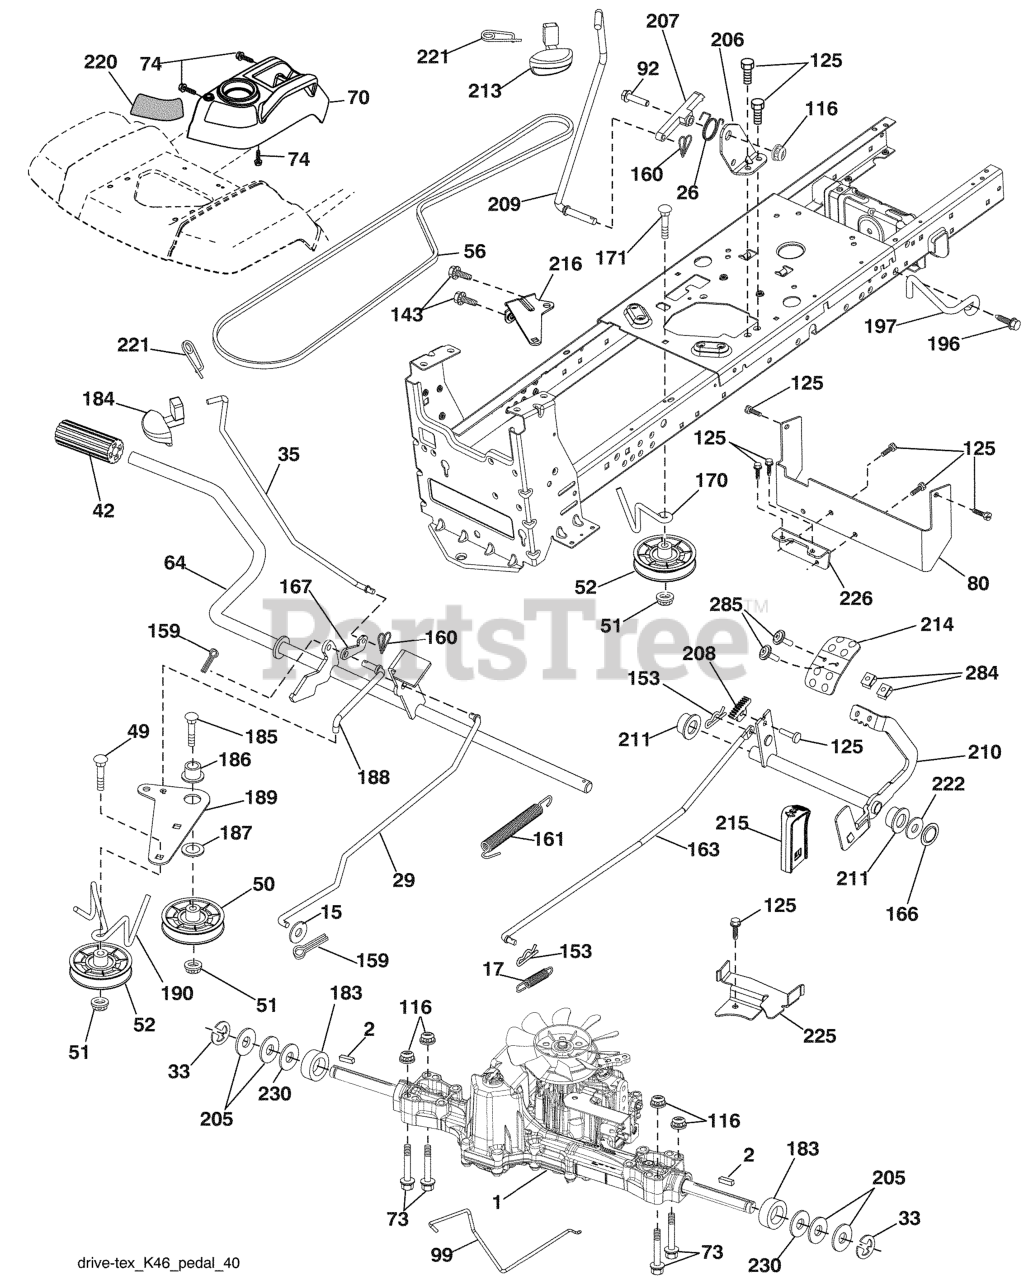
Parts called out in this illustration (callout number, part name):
1	RP TRANSAXLE (K46CR) ETC.PDL
2	SQUARE KEY
15	WASHER
17	SPRING.BRAKE.K46.GREEN
26	SPRING.RETURN.CRUISE
29	ROD.BRAKE.K46
35	ROD.BRAKE.PARKING.GT.H
42	PEDAL COVER T
50	IDLER.FLAT.910.OFFSET
51	NUT LOCK FLG 3/8-16 UNC
52	IDLER.V-GROOVE.910.OFFSET
56	V-BELT.MOWER.92.40.42/K46
64	SHAFT.ASM.PEDAL.BRK.CNTR
70	RP CONSOLE.ASM.PCH.W/TB
73	BOLT HEX 5/16-18 GR 5
74	SCREW.HI-LO.CONSOLE
80	STRAP TORQUE.ASM.K46/18"TEX
92	BOLT
99	ROD.SPRING.BYPASS.K46.LT.Z
116	NUT LOCK HEX FLANGE 5/16-18
125	SCREW
143	Screw 5/16-18 x 1/2
153	RETAINER M
159	COTTER PIN
160	RETAINER CLIP
161	SPRING, RETURN LT
163	ROD.CONTROL.PEDAL.K46
166	NUT.PUSH.625.2006
167	LATCH.BRAKE.SPRING
170	KEEPER.V-IDLER.CENTER.
171	BOLT
183	SPACER AXLE
184	HANDLE.PARKG.BRK.HUSQ X667
186	SPACER.RETAINER
187	WASHER 12/32X2X10GA
188	RP.LINK.CLUTCH.GROUND.DRIVE
189	BELLCRANK.GROUND.DRIVE.TEX.
190	KEEPER.BELLCRANK.DRIVE
196	SCREW 3/8-16X1
197	LINK.CLUTCH.ANIT-ROTAT
206	BRKT.MOUNT.LATCH.CRUIS
207	LATCH.CONTROL.CRUISE
208	GEAR.SECTOR.CONTROL.CR
209	ROD.CONTROL.CRUISE.GT.
210	ROCKER.ASM.PEDAL.CONTR
211	BEARING.NYLON
213	KNOB.CONTROL.CRUSIE.HU
214	PEDAL.FORWARD.HUSQVARNA.DEALER
215	PEDAL.REVERSE.TEX.GT.4
216	BRACKET.PULLEY.IDLER.W/TEX
220	REFLECTOR.RH.TEX GT
221	RETAINER.SPRING.CLIP.H
222	WASHER 21/32 X 1-1/4 X 10 GA.
225	KEEPER.BELT.TRANSAXLE.K46
226	BRACKET.MOUNT.TORQUE.K46.TLT
230	WASHER.HARDENED
284	NUT.U-CHNL.1/4-20.550DP.350PNL
285	SCREW.PHD.1/4-20.BOX DRVE
